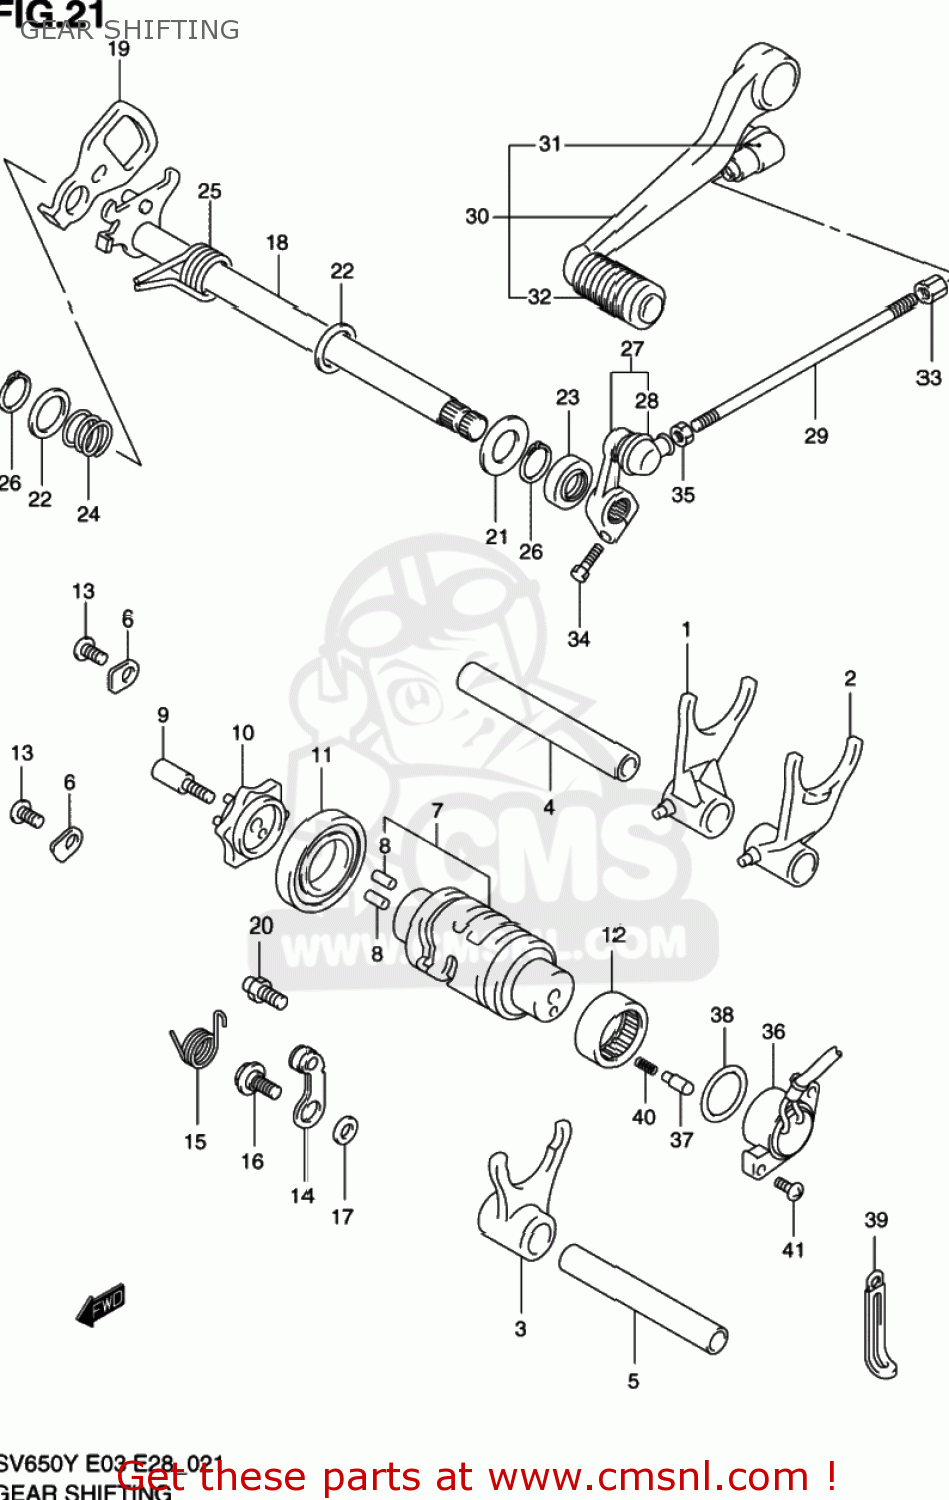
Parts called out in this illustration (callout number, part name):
1	FORK,GEAR SHIFT NO.1
2	FORK,GEAR SHIFT NO.2
3	FORK,GEAR SHIFT NO.3
4	SHAFT,GEAR SHIFT FORK
5	SHAFT,GEAR SHIFT FORK NO.1
6	RETAINER
7	CAM,GEAR SHIFT
8	PIN
9	PIN,SHIFT CAM DRIVEN GEAR
10	PLATE,GEAR SHIFT CAM
11	BEARING(25X47X8)
12	BEARING(25X32X12)
13	SCREW
14	STOPPER,GEAR SHIFT CAM
15	SPRING,STOPPER ARM
16	BOLT(6X14.3)
17	WASHER
18	SHAFT,GEAR SHIFT
19	PLATE,GEAR SHIFT CAM DRIVE
20	STOPPER,GEAR SHIFT CAM
21	WASHER(14X29X0.8)
22	SHIM(14X22X1)
23	SEAL,OIL(14X22X6)
24	SPRING
25	SPRING
26	CIRCLIP
27	ARM,GEAR SHIFT LINK
28	COVER,DUST
29	ROD,GEAR SHAFT LINK
30	LEVER ASSY,GEAR SHIFT
31	COVER,DUST
32	RUBBER,GEAR SHIFT PEDAL
33	NUT
34	BOLT
35	NUT
36	BASE ASSY,GEAR SHIFT TERMINAL
37	PIN(5X15.5)
38	O RING(D:2.4,ID:25.7)
39	CLAMP(L:65 T:0.8)
40	SPRING
41	SCREW
